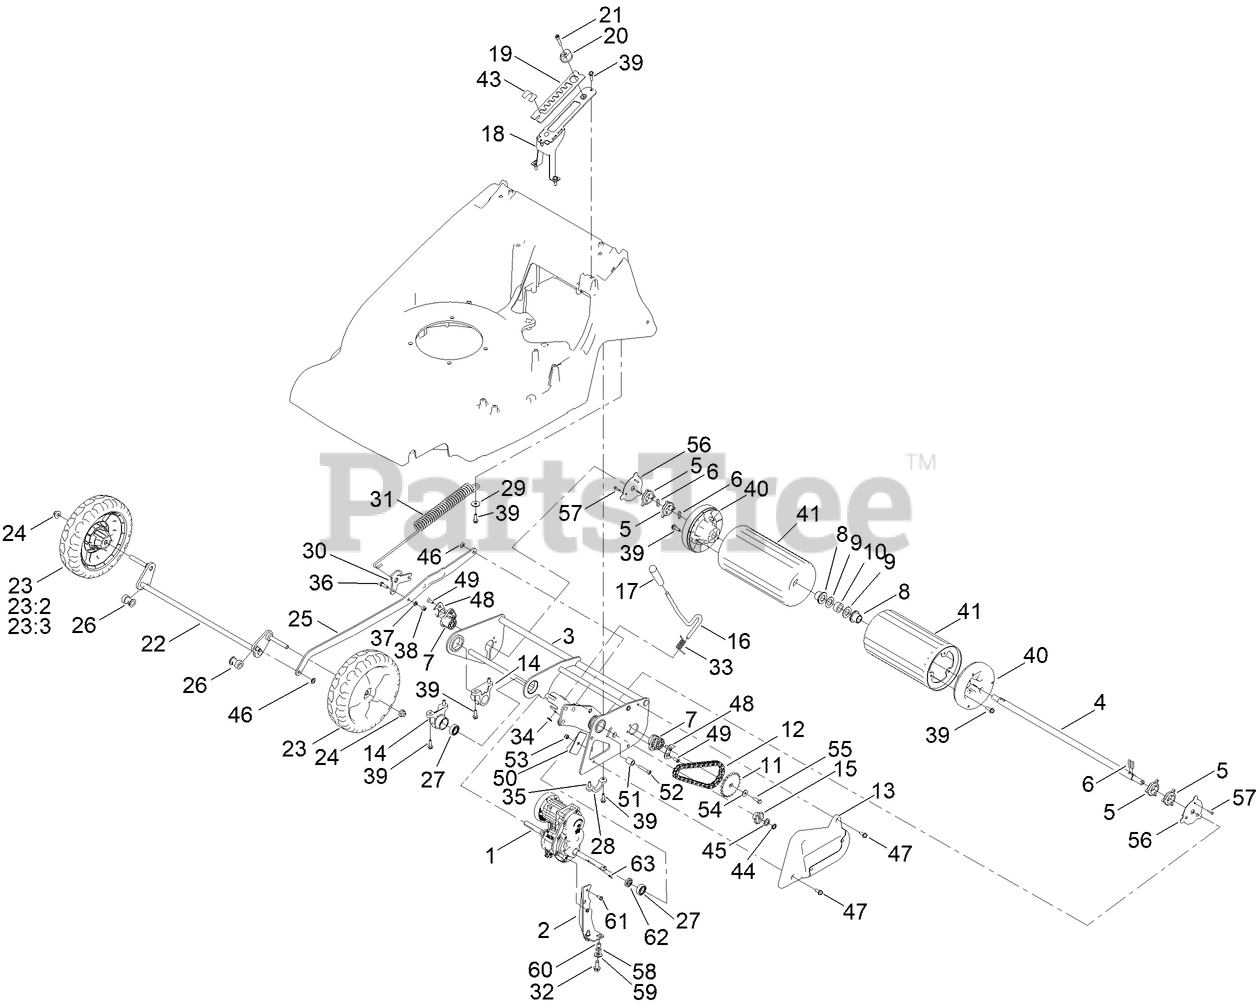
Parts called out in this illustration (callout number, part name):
1	GEARBOX, ME622
2	BRACKET, E-GEARBOX [BLACK
3	REAR FRAME, 56 (PRO)
4	SHAFT-ROLLER, PRO
5	CAM-DRIVE
6	KEY-DRIVE
7	BUSH, REAR ROLLER
8	BUSHING-ROLLER, OILITE
9	WASHER
10	SPACER-ROLLER
11	SPROCKET
12	CHAIN(46 PITCHES 3/8")
13	CHAIN COVER ASM
14	MOUNT-BEARING, FRAME (REAR)
15	SPROCKET, 10T
16	LEVER-HOC
17	KNOB-HOC
18	HOC TOWER ASSEMBLY
19	PLATE-HOC
20	ADJUSTER-HOC
21	SCREW-HSH
22	56 FRONT AXLE ASSEMBLY HD
23:2	BEARING-BALL
23:3	SPACER
24	NUT-HF, NI
25	CONNECTING ROD ASSEMBLY
26	BEARING-AXLE, FRONT
27	BEARING, BALL 12MM
28	AXLE- SUPPORT, REAR
29	WASHER
30	SPRING LOAD LEVER
31	SPRING COUNTER BALANCE
32	SCREW-HWH
33	SPRING-TORSION, HOC
34	GRIP-FIX
35	SCREW
36	SCREW-HH
37	WASHER-PLAIN
38	NUT-NYLOC
39	SCREW-TAPTITE
40	CAP-ROLLER, END
41	ROLLER SHELL ASSEMBLY
43	DECAL-HOC
44	CIRCLIP-EXTERNAL, HD
45	WASHER-THRUST
46	WASHER-STARLOCK
47	SCREW-TAPTITE
48	BEARING SUPPORT PLATE
49	SCREW-TAPTITE
50	BACK PLATE, TENSIONER
51	PULLEY, TENSIONER
53	NUT-NYLOC
54	WASHER-PLAIN
55	SCREW-HH LOCK
56	COVER, BEARING
58	O-RING
59	WASHER-PLAIN
60	BUSH, E-GEARBOX BRACKET
61	SCREW-PLASTIC,PHT
62	RETAINING COLLAR, DRIVE SHAFT
63	PIN, ROLL, 3MM X 16MM
